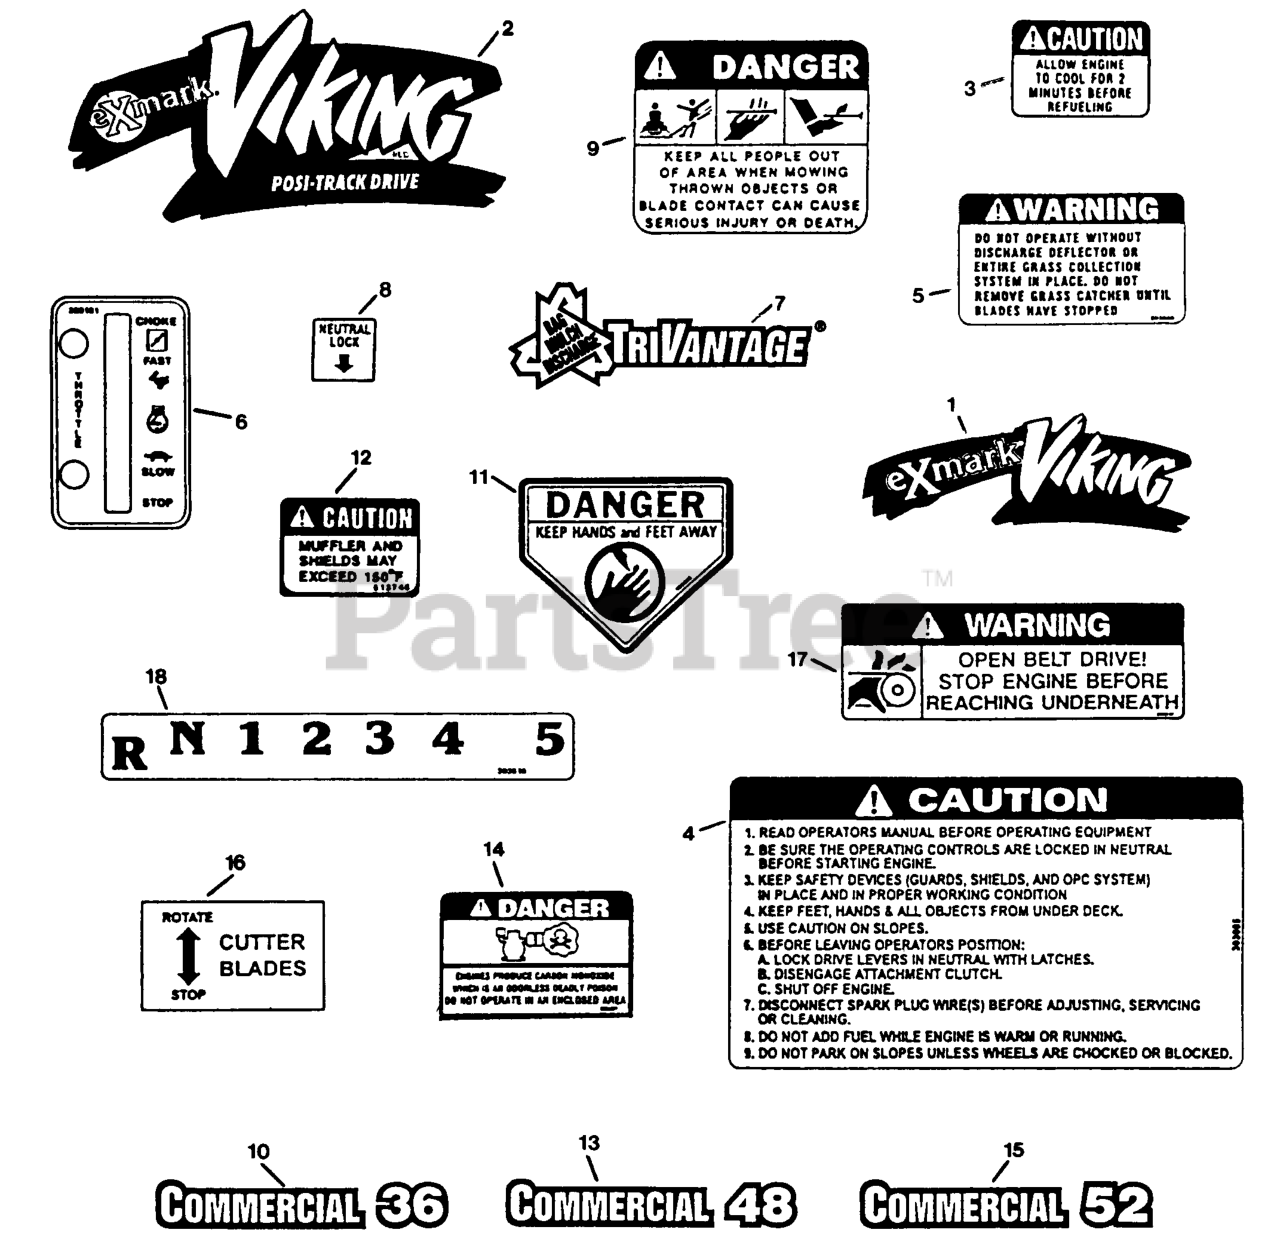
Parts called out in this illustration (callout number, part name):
4	LABEL,INSTRUCTION
5	DECAL-WARNING, DISCHARGE
8	DECAL,NEUTRAL LOCK
9	DECAL-DANGER
10	DECAL,COMMERCIAL 36
11	DECAL-DANGER
13	DECAL,COMMERCIAL 48
15	DECAL,COMMERCIAL 52
16	DECAL,CUTTER BLADE
17	DECAL,BELT DRIVE
18	DECAL,SHIFTER
